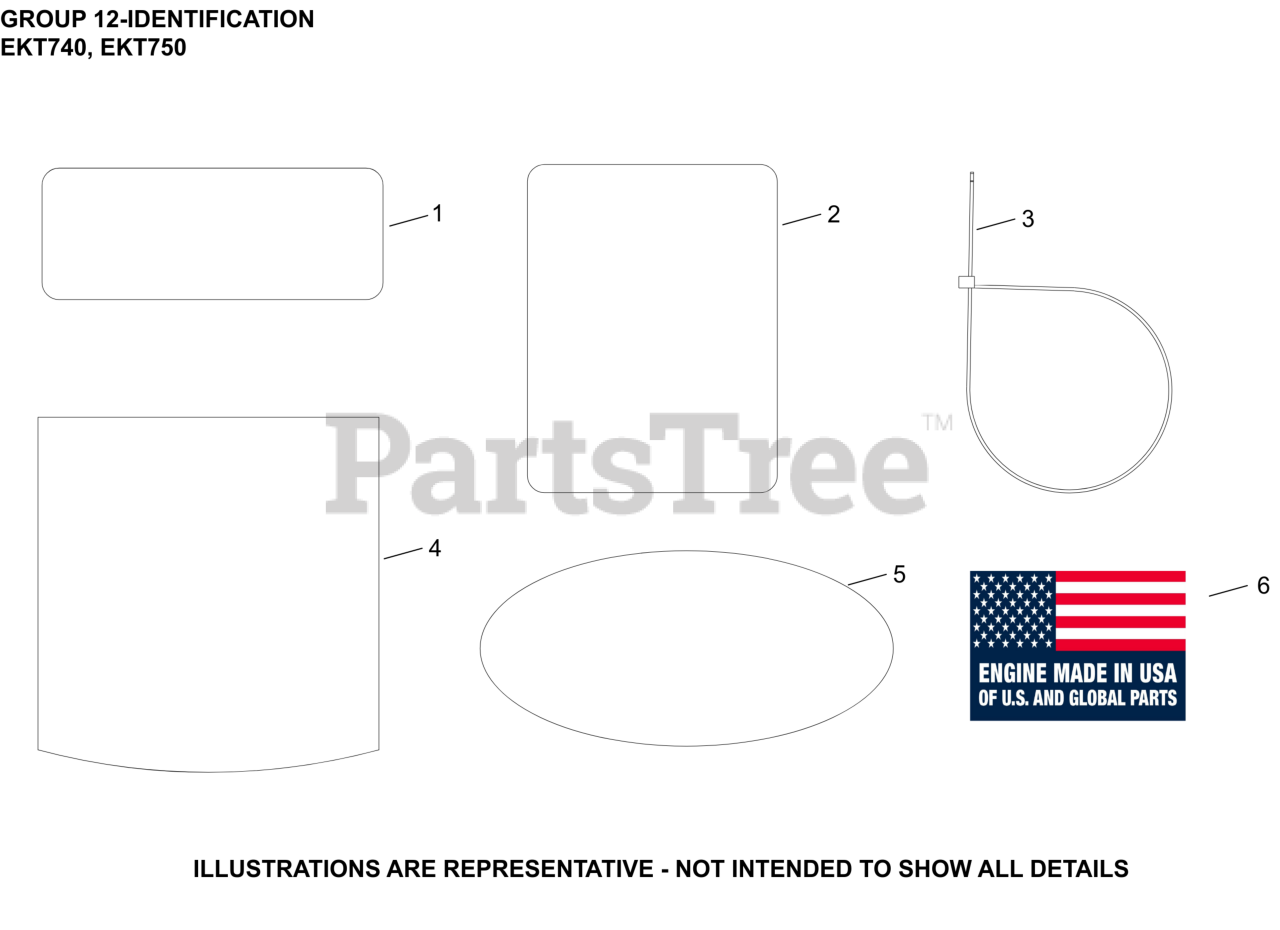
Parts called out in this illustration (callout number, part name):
1	LABEL, CANADIAN COMPLIANCE
2	LABEL, CLEAR LAMINATION
4	27HP - 7500 SERIES PRO EFI - DECAL
6	DECAL, USA
